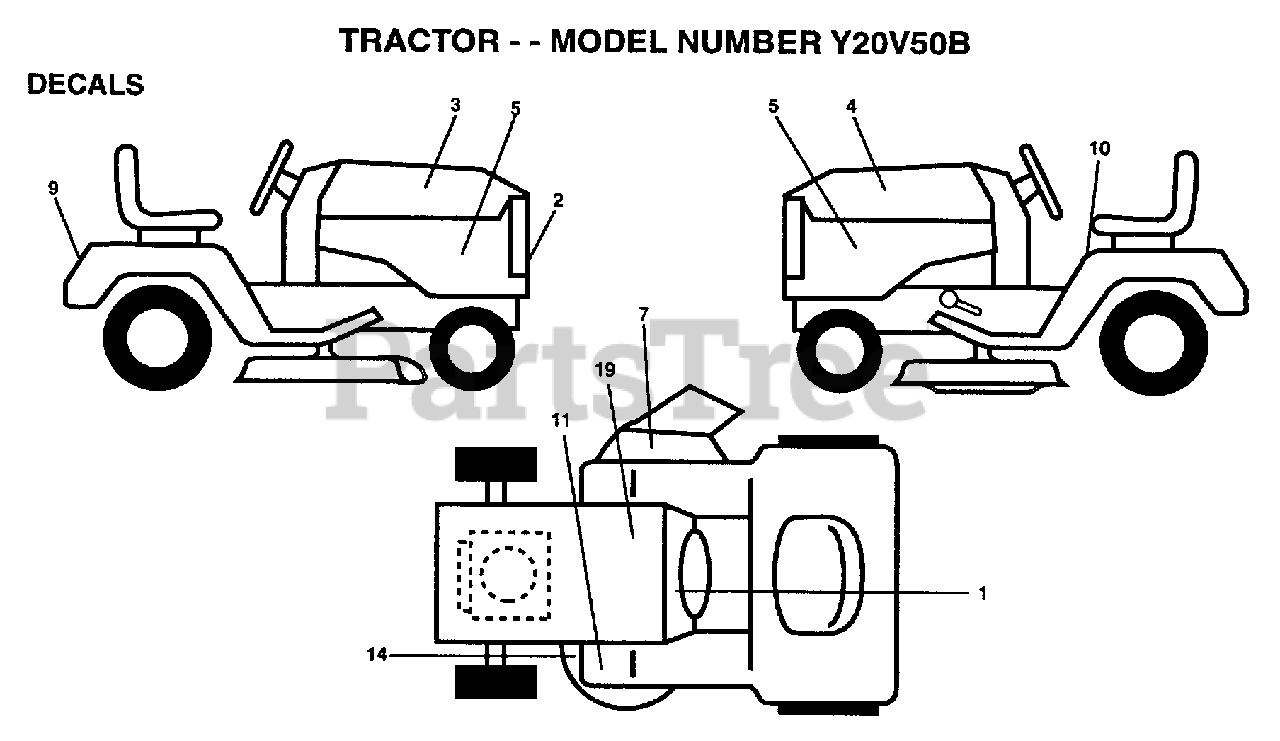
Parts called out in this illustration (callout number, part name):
1	DECAL.DASH.INSTR.
2	DECAL.GRILL.YARDP
4	DECAL HOOD LH
5	DECAL.PNL.SIDE.20
7	"DECAL, WARNING"
10	DECAL CAUTION
11	DECAL T
14	"DECAL.V.BELT.44"""
19	DECAL
